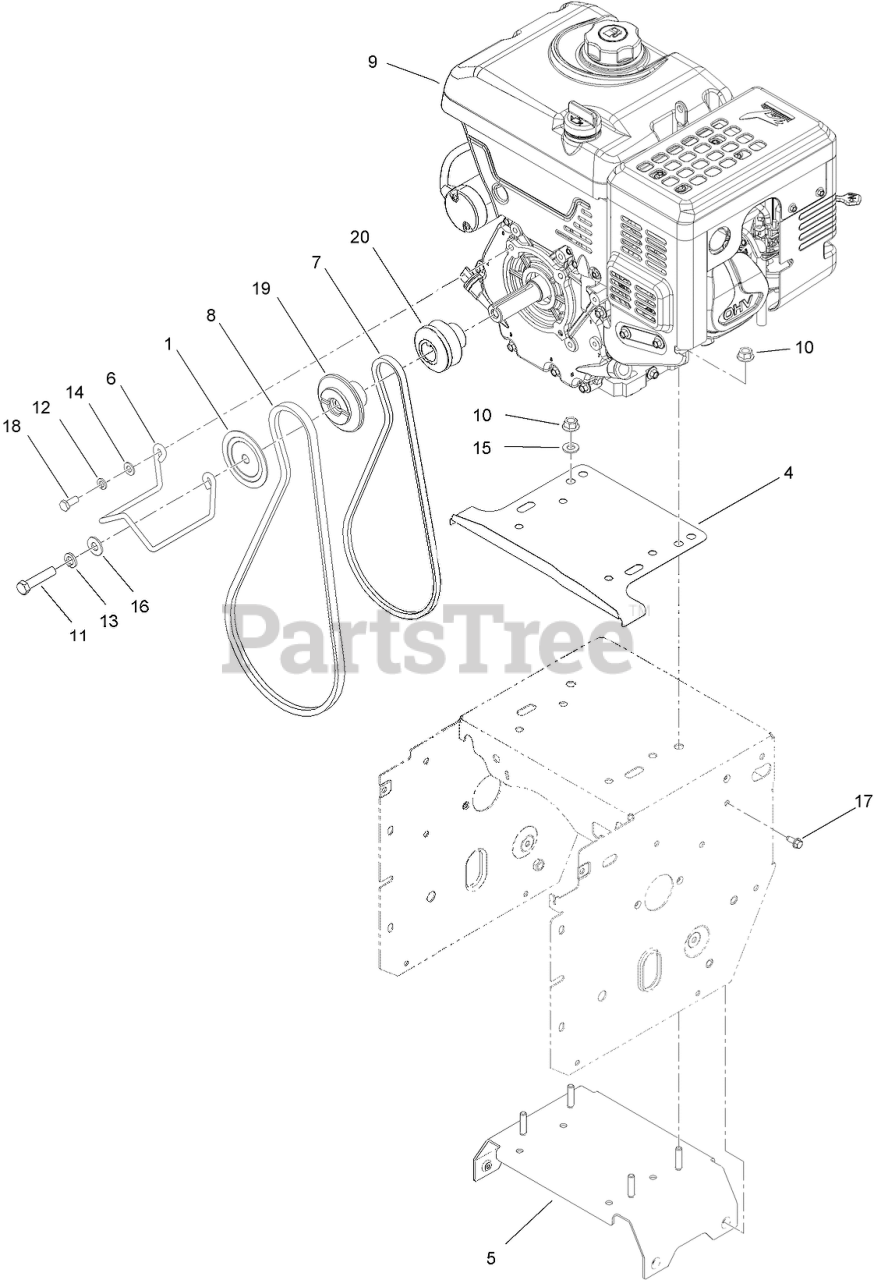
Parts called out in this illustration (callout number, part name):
1	SHEAVE-HALF, IMPELLER
4	SHIELD-DRIVE
5	FRAME BRACE ASM
6	GUIDE-BELT
7	BELT-V
8	BELT-V
9	ENGINE-180FDS-1
10	NUT-FLANGE
11	SCREW-HH
12	WASHER-LOCK
13	WASHER-LOCK
14	WASHER-PLAIN
15	WASHER-FLAT
16	WASHER-FLAT
17	SCREW-HWH
18	SCREW-HH
19	PULLEY-ENGINE, IMPELLER
20	PULLEY-TRACTION
